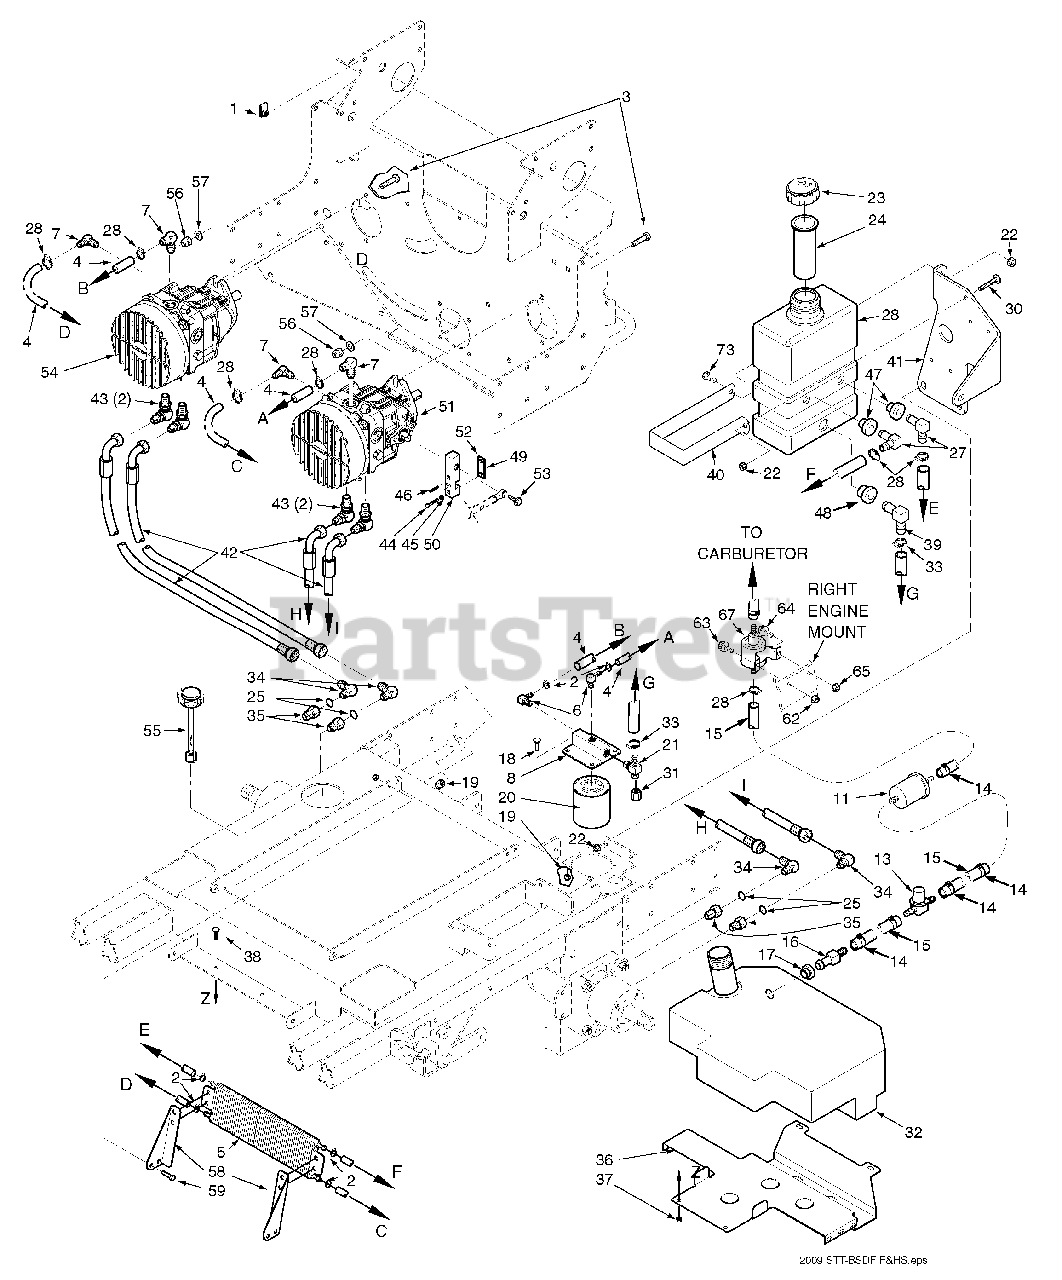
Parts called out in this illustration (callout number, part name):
1	U-Nut 1/4-20
2	Hose Clamp, 0.69" Dia.
3	Bolt, Hex Hd. 1/4-20 x 2.0"
4	Hose, 3/8" ID Pushlock
5	Oil Cooler
6	Elbow, 90 Deg. - 1/4" NPT x 3/8" Hose
7	Elbow, 90 Deg. - 9/16" O-ring x 3/8" Hose
8	Oil Filter Base
9	Hose Assy, 1/2" ID (Tank to Filter Base)
10	Clamp, .87" max Dia.
11	Fuel Filter, Kubota
12	Fuel Hose, 5/16" ID. Non-Perm.
13	Valve, Shutoff
14	Clamp, 5/16" Fuel Hose
15	Fuel Hose, 5/16" ID. Non-Perm.
16	Hose Fitting
17	Bushing
18	Bolt, Hex Hd. 5/16-18 x 1.0" Zinc
19	Nut, Serr. Flng. 5/16-18
20	Oil Filter
21	Tee, 3/4" O-Ring x JIC x 1/2" Hose
22	Nut, Hex Elastic Stop 1/4-20
23	Cap, Hydraulic Tank
24	Insert, Filler Neck
25	O-Ring
26	Oil Reservoir Assembly
27	Elbow, 90 Deg. 0.38" Hose
28	Hose Clamp, 0.69" dia.
29	Hose, 3/8" ID, Pushlock
30	Screw, Phillips Head, 1/4-20
32	Fuel Tank Assembly
33	Clamp, Hose
34	Elbow, 90 Deg., 5/8 x 1/2"
35	Bushing, 7/8"-14 JIC x 3/4"-16 O-Ring
36	Support Bracket, Fuel Tank
37	Nut, 5/16-18 Serr. Flng.
38	Bolt, Carriage 1/4-20 x 3/4"
39	Elbow, 90 Deg.
40	Strap, Hydraulic Tank
41	Support Bracket, Hydraulic Tank
42	Hose Assembly, Pump
43	Union, 5/8 x 1/2
44	Bolt, Hex Hd., 1/4-20 x 1-1/4"
45	Lockwasher, 1/4" Spring
46	Roll Pin, Spring 3/16 x 3/4"
47	Bolt, Hex Serr. Flng., 1/4-20 x 3/4"
48	Fuel Hose, 5/16" ID. Non-Perm.
49	Clamp Plate, Pump Control
50	Block, Pump Control
51	Pump, Left Hand, BDP-16A
52	Nut, Hex, Elastic Stop 3/8-16
53	Bolt, Hex Hd., 3/8-16 x 1-1/4
54	Pump, Right Hand, BDP 16A
55	Cap, Fuel Tank w/Gauge
56	Nut, Hex Elastic Stop 3/8-16
57	Flatwasher, 3/8" (.391 x .938 x .105") Grd.
58	Mounting Bracket - LH, Oil Cooler
59	Bolt, Hex Hd. 5/16-18 x 3/4"
60	Cooler, Oil
61	Clamp, 0.69" Dia.
62	Nut, Serr. Flng. 5/16-18
63	Bolt, Hex Hd. 5/16-18 x 3/4"
64	Bolt, Hex Hd. 1/4-20 x 3/4"
65	Nut, Serr. Flng. 1/4-20
